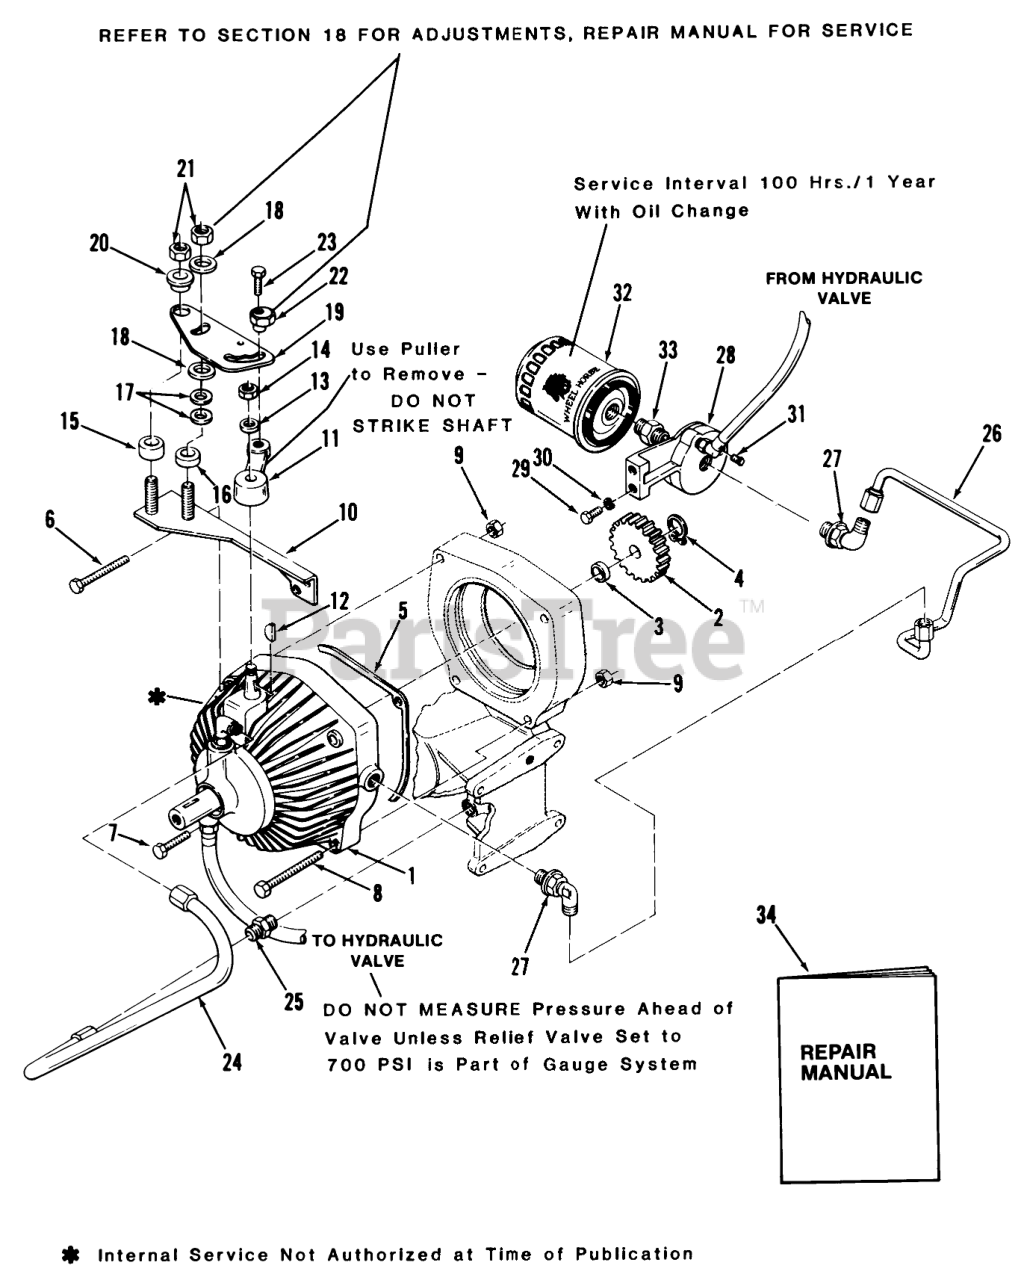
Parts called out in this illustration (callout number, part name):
1	Pump & Motor
2	GEAR 22T DRIVE
3	SPACER GEAR
4	SNAP RING- 5/8 EXT
5	GASKET
6	H H C S
7	Bolt
8	Bolt 3/8-16 x 6 1/2
9	Nut
10	ASSY-PLATE B
11	ARM-SPEED CONTROLB
12	Key #5 Woodruff
13	Washer
14	Eslok Nut
15	SPACER-PIVOT
16	SPACER-FRICTION
17	WASHER-SPRING DISC
18	FRICTION WASHER
19	CAM-SPEED CONTROL (NS)
20	CAM-SPACER
23	Bolt
24	ASSY-TUBE SUCTION
25	FITTING-TUBE
26	ASM-TUBE FILTER OUTL
27	ELBOW
28	BASE-FILTER
29	Bolt
30	Lockwasher
31	PLUG 1/4 PIPE ALLEN
32	Filter-Oil
33	FITTING
34	Repair Manual
